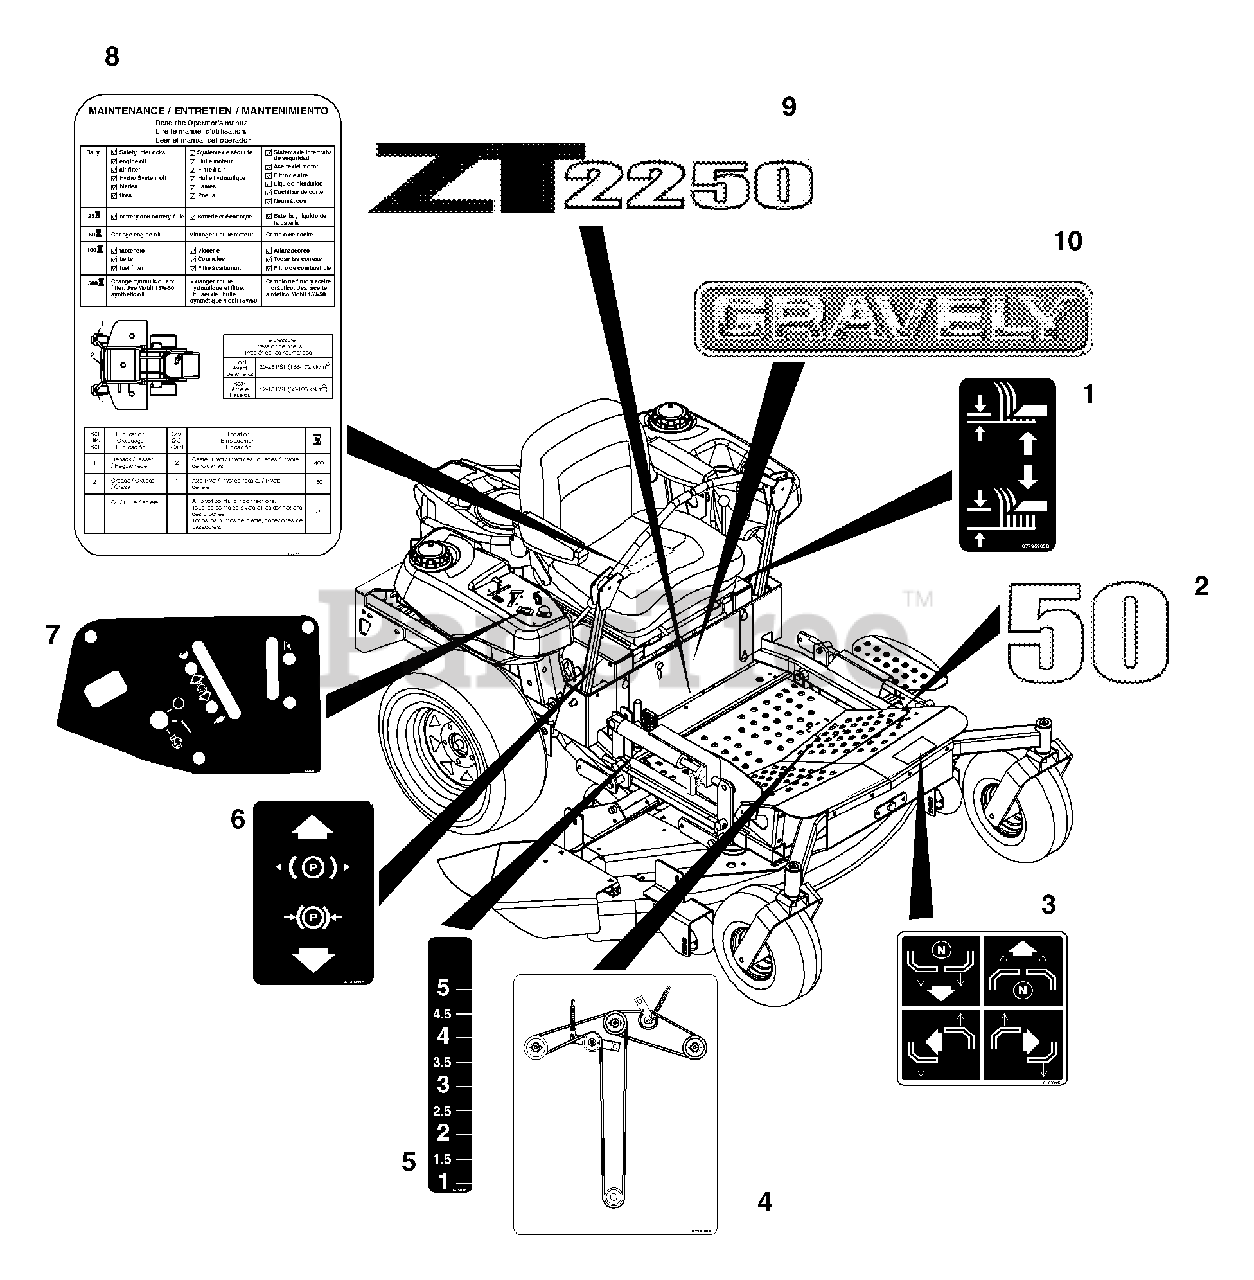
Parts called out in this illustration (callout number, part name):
1	Decal- Lift Lever
2	Decal, 50
3	Decal-Instructional-Steering
4	Decal, Belt Diagram
5	Decal, Height of Cut
6	Decal-Parking Brake Lever
7	Decal, Control Panel
8	Decal- Service Instructions
9	Decal, Gravely ZT 2250
10	Decal, 15"Gravely Logo
